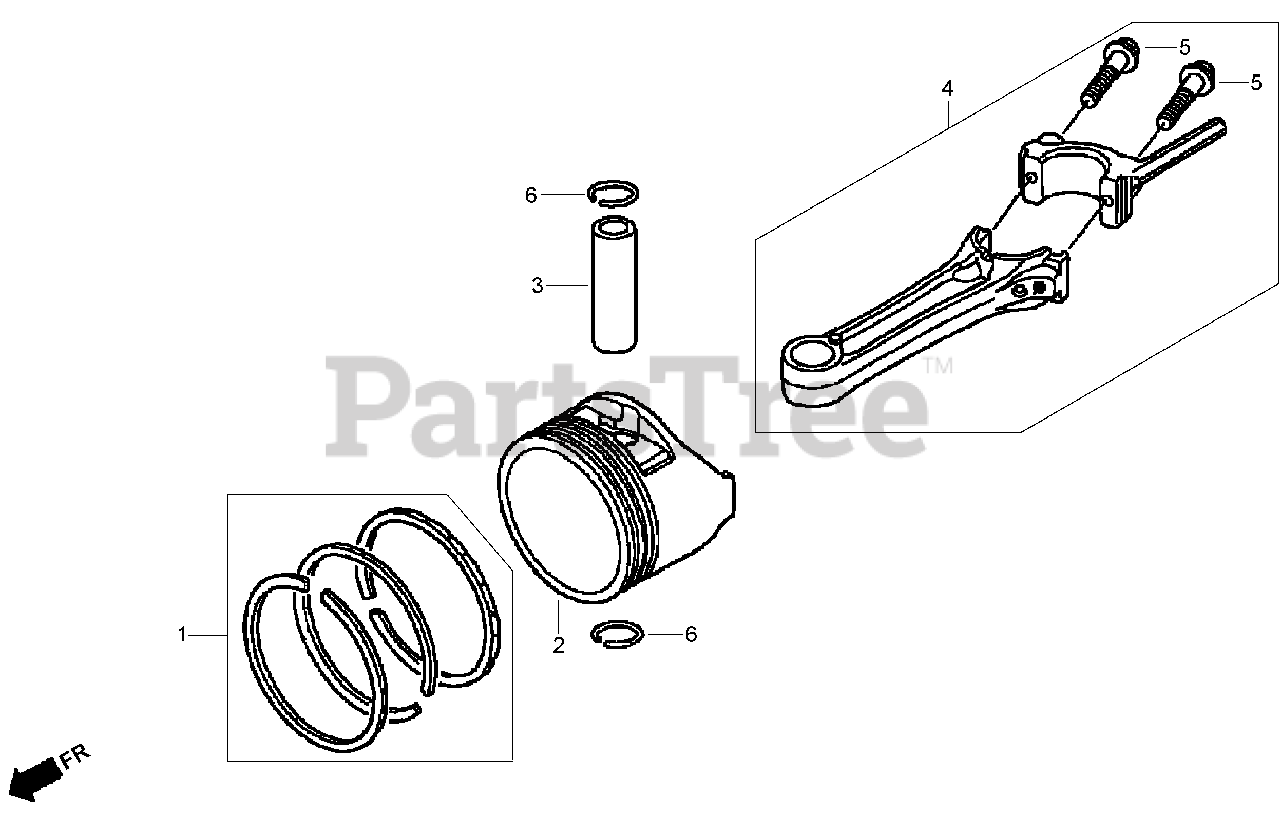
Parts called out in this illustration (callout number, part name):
1	PISTON RING SET (STD) (TEIKOKU)
2	PISTON
3	PIN-PISTON
4	CONNECTING ROD ASM
5	BOLT-ROD, CONNECTING
6	CLIP-PIN, PISTON (13MM)
